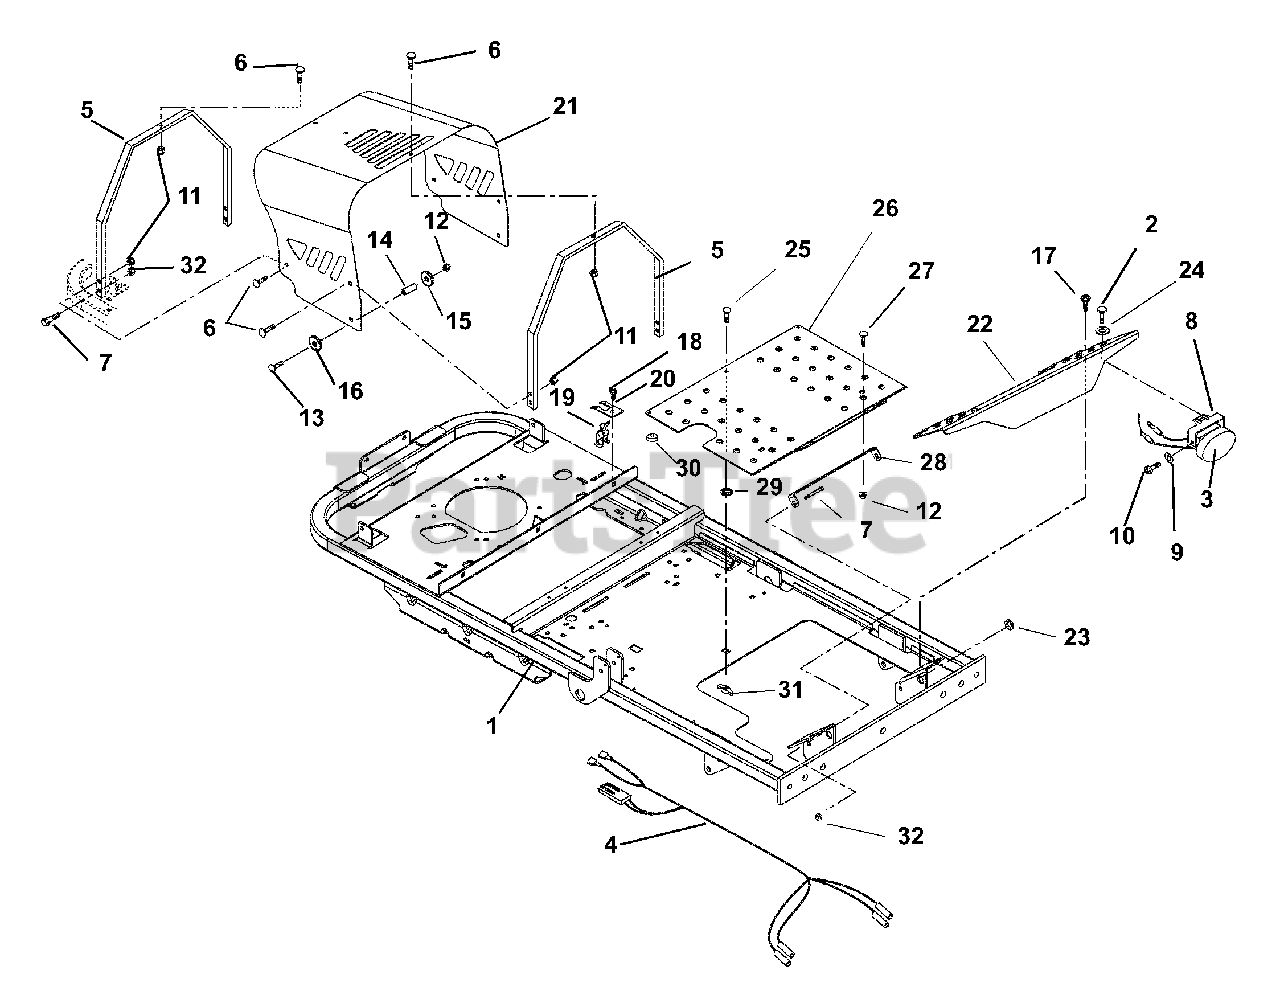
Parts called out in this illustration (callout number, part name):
1	Weldment, Frame
2	Screw-Cap Button Head .31-18 x .50 Grade 5
3	Assembly, Light
4	Harness, Light
5	Brace, Hood
6	Bolt, Round Head Square Neck .31-18 x .62
7	Bolt, Shoulder .375-16 x .135
8	Bracket, Light
9	Washer, Locking 4MM x 1MM Regular Cone Lock
10	Screw, Socket Head Cap M4 x .07 x 8
11	Nut-Locking-Top-Flange .31-18
12	Nut, .38-16 Flange Nyloc
13	Bolt, Round Head Square Neck .38-16 x 2.00 Grade 5
14	Hood Snap
15	Washer, Flat Steel .375 x 1.125 x .065
16	Washer, Flat Steel .531 x 1.06 x .095
17	Screw, Tap .31-18 x .50
18	Screw, Tap .25-20 x .50
19	Hood Clip
20	Bracket, Hood Clip
21	Hood, Zoom
22	Foot Rest
23	Grommet, Rubber .38 I.D.
24	Washer, Locking .31 x .078
25	Bolt, Round Head Square Neck .31-18 x 1.00 Grade 5
26	Plate, Deck Access
27	Bolt, Round Head Square Neck .38-16 x 1.00 Grade 5
28	Bracket, Deck Access
29	Nut, Push .312
30	Grommet, Bumper
31	Knob, Wing .312-18
32	Nut-Locking-Top-Flange .31-16
